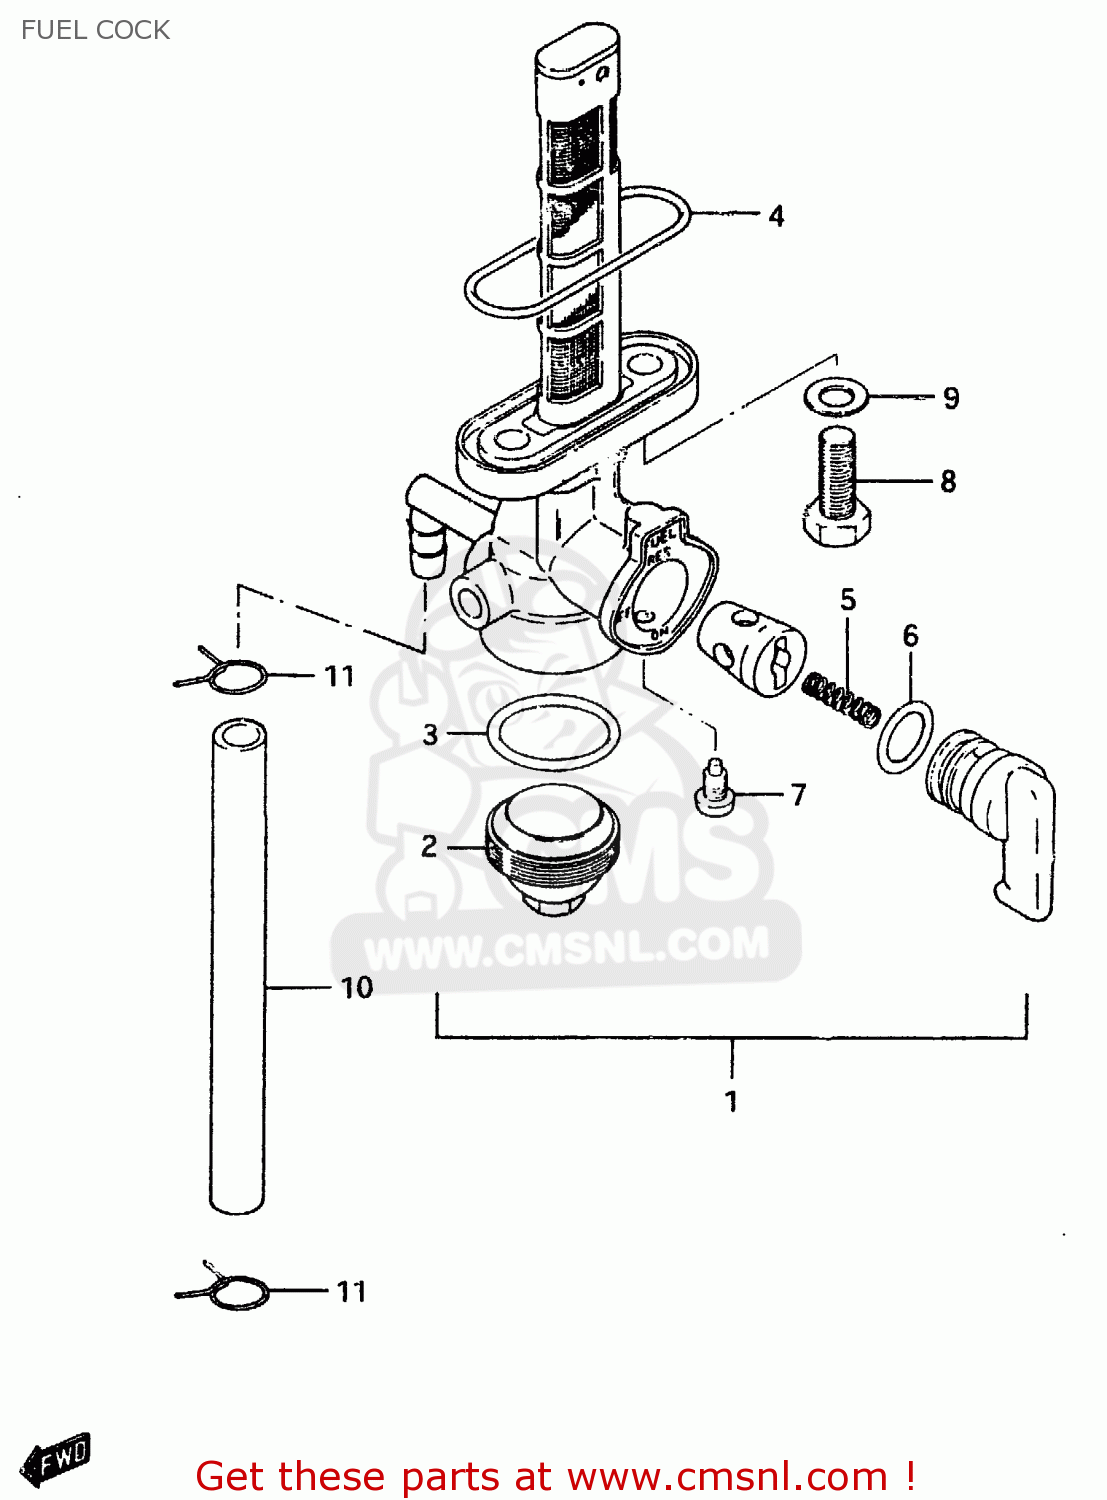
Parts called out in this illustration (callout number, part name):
1	COCK ASSY, FUEL
2	CUP,STRAINER
3	GASKET,FILTER (NAS)
4	O RING,FUEL COCK
5	SPRING
6	O-RING
7	SCREW
8	BOLT(6X20)
9	GASKET
10	HOSE
11	CLIP
